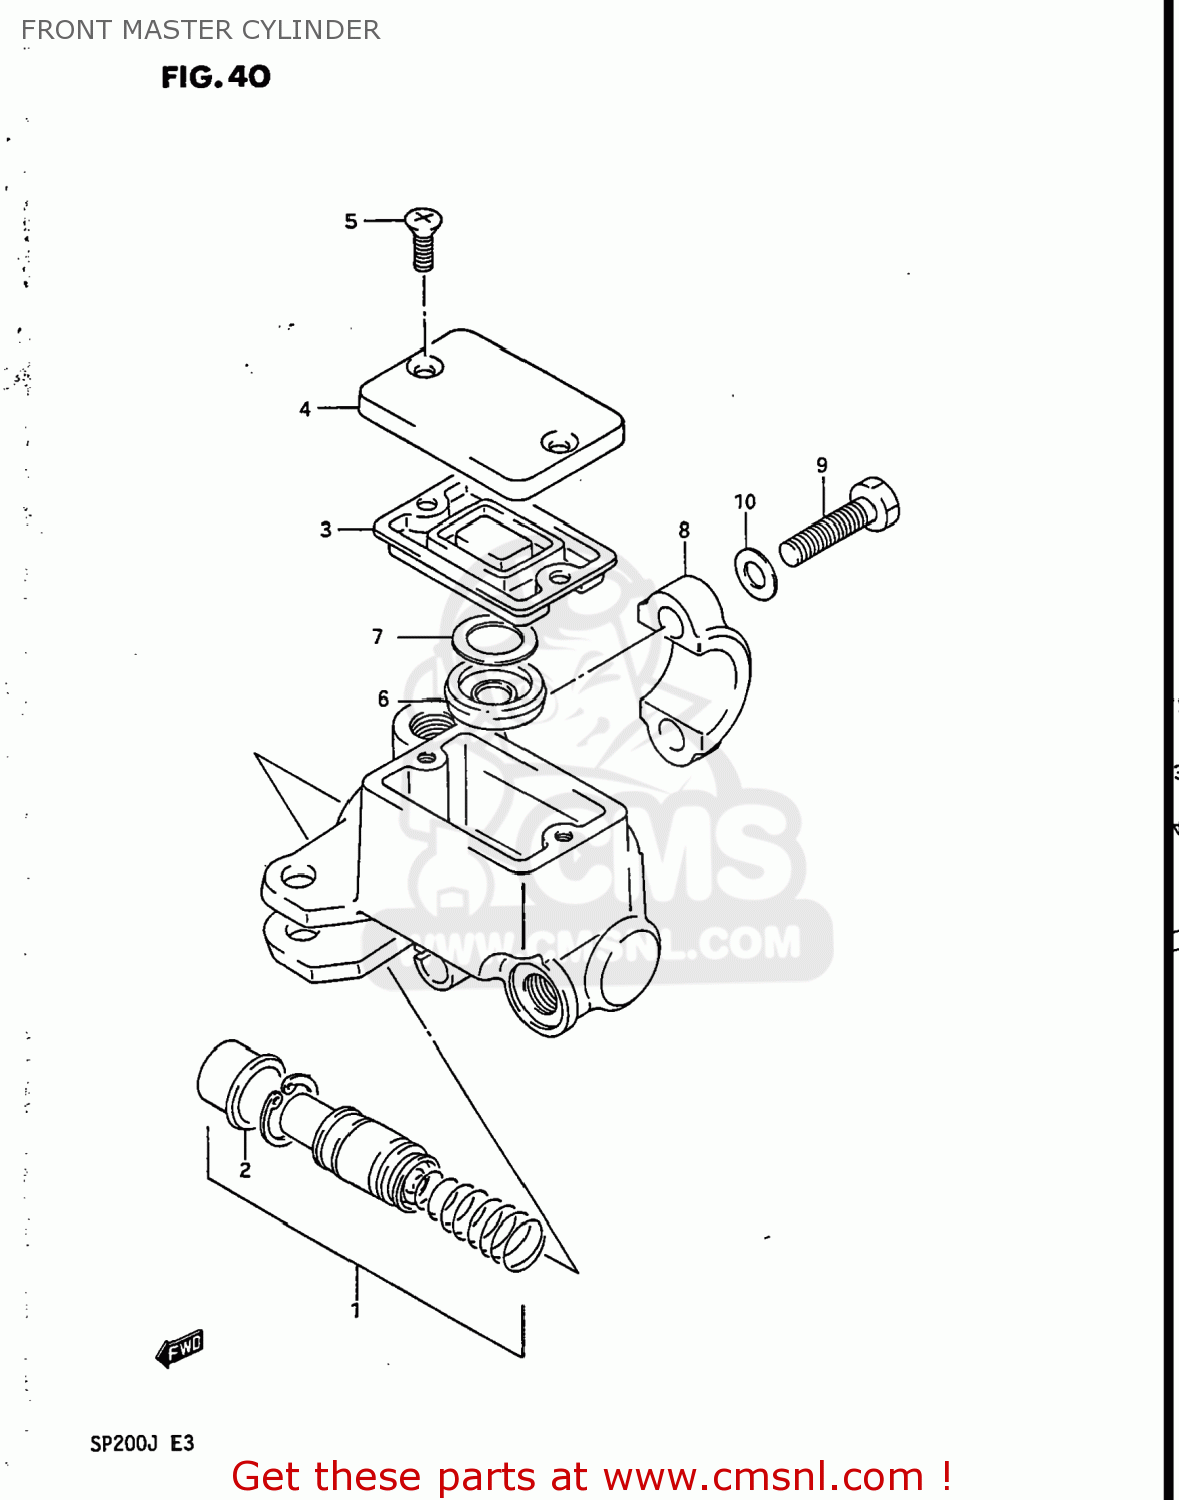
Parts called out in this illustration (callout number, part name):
1	PISTON/CUP SET
2	BOOT
3	DIAPHRAGM
4	CAP
5	SCREW
6	SEPERATOR
7	PLATE
8	HOLDER
9	BOLT
10	WASHER
